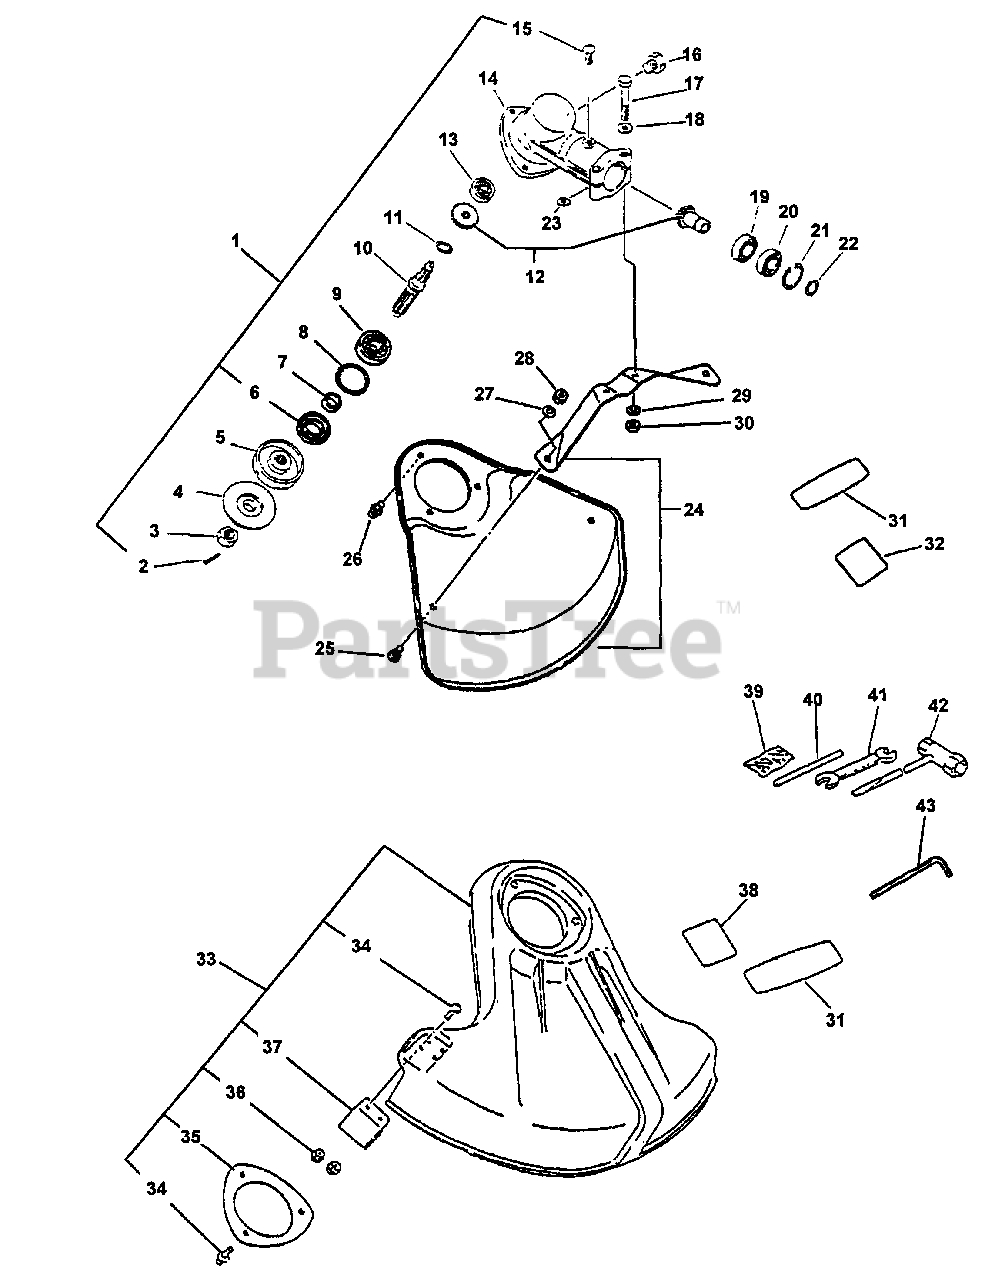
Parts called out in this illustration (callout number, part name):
1	CASE, GEAR - UPPER
2	PIN, COTTER 2×22
4	PLATE, ADAPTOR - LOWER
5	PLATE, ADAPTER - UPPER
6	SEAL, OIL 22
7	SPACER 11.8×15×9
8	RING, SNAP Ø32
9	BEARING, BALL - 6201 C3
10	SHAFT, GEAR
11	RING, SNAP Ø10
12	GEAR SET
13	BEARING, BALL 609
14	HOUSING, GEAR CASE
15	SCREW 5×10
16	BOLT 8×8 SP
17	BOLT 5×35 SP
18	WASHER, FLAT 5.5×10×0.8
19	BEARING, BALL 6900
20	BEARING, BALL 6900Z
21	RING, SNAP Ø22
22	RING, SNAP Ø12
24	SHIELD ASSY
25	SCREW 5×8
26	SCREW 5×10
27	WASHER, SPRING 5
28	NUT M5
29	WASHER, SPRING 5
30	NUT M5
31	LABEL, ECHO
32	LABEL, DANGER
33	DEBRIS SHIELD KIT
34	SCREW 5×16
35	PLATE, SHIELD Ø49.5 MM
36	NUT M5
37	CUTTER, LINE
38	LABEL, CAUTION
39	PIN, COTTER 2×22 (PKG. OF 10)
40	TOOL, LOCKING 5×120 MM
41	SPANNER 8×10
42	T-WRENCH 17x-19 L200
43	WRENCH, ALLEN 3 MM
